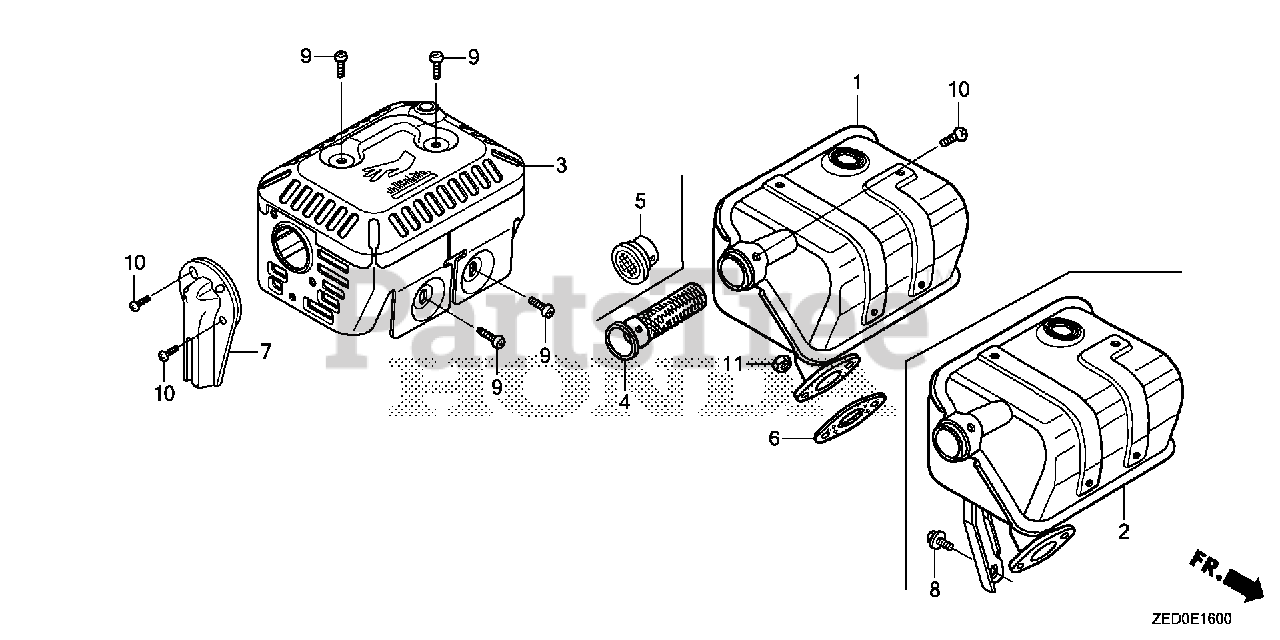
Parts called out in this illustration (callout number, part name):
1	MUFFLER (ARRESTER)
3	PROTECTOR, MUFFLER (STD)
4	ARRESTER, SPARK
6	GASKET, MUFFLER
6	GASKET, MUFFLER (NINGBO SIL GASKET)
8	BOLT, FLANGE (6X13)
9	SCREW, TAPPING (5X8)
10	SCREW, TAPPING (4X6) (TO INSTALL OPTIONAL SPARK ARRESTER)
11	NUT, HEX. (8MM)
